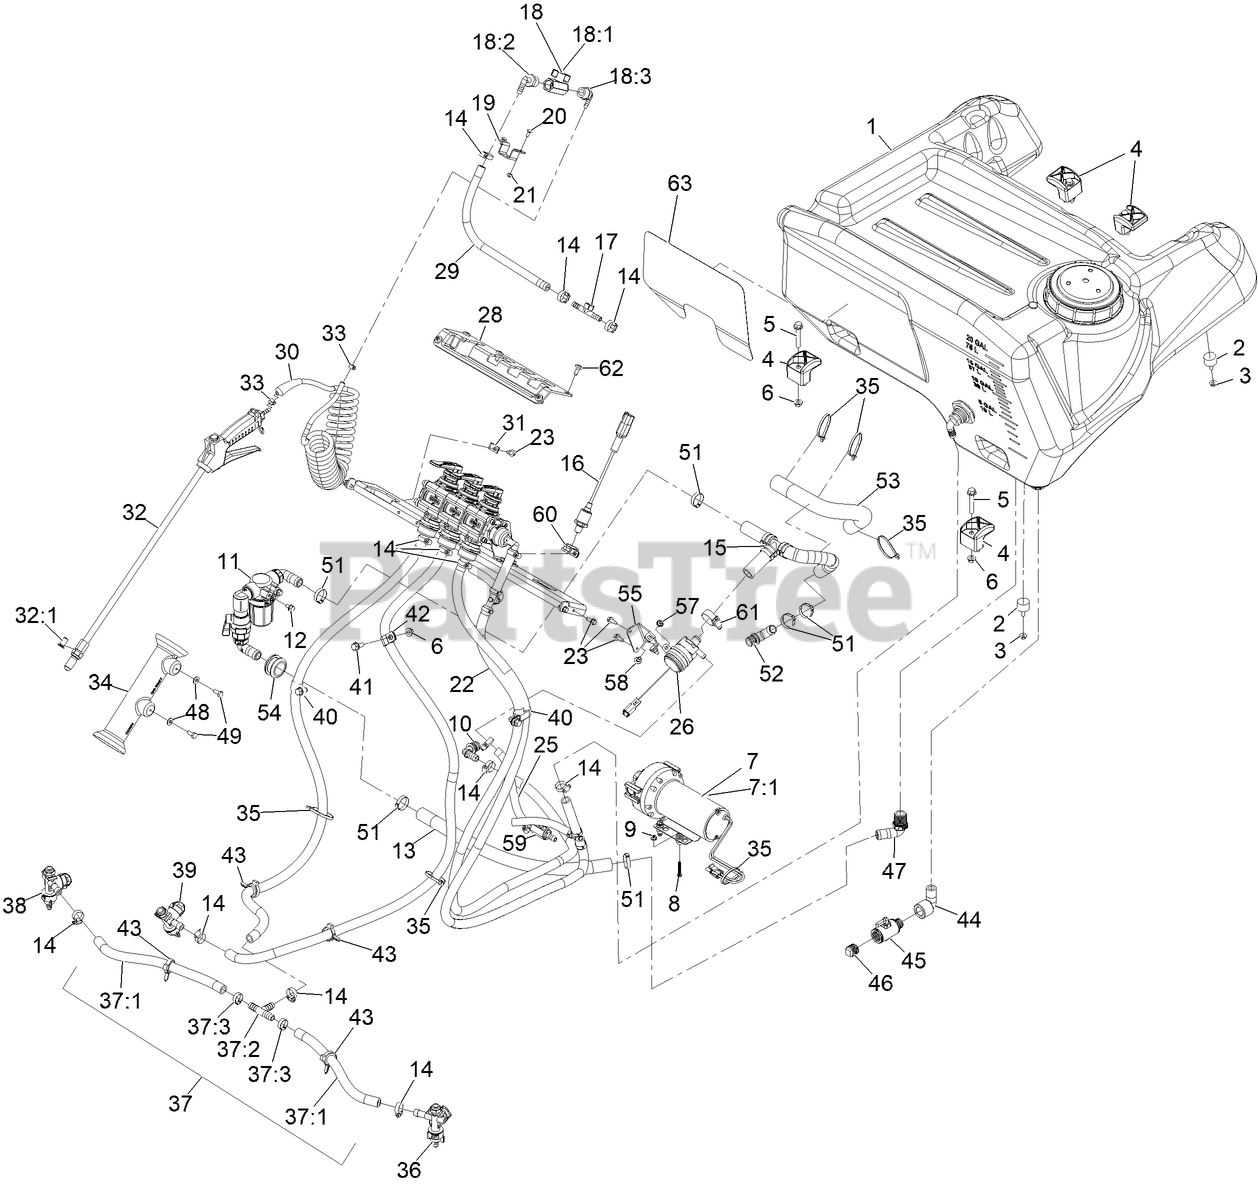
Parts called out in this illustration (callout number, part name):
1	Tank-Sprayer
5	SCREW-HHF
7	Pump-Diaphragm, 3.8 GPM
7:1	KIT-DIAPHRAM PUMP
8	SCREW-SHWH
10	FITTING-ELBOW, BARBED
11	STRAINER ASM
12	SCREW-HHF
13	HOSE-WATER
14	CLAMP-HOSE
15	ASM-, 3/4 Pvc Reinforced Water Hose
16	TRANSDUCER-PRESSURE
17	FITTING-TEE
18	Wand Control ASM
18:1	VALVE-BALL
18:2	FITTING-ELBOW-90
18:3	FITTING-ELBOW-90
19	BRACKET-VALVE
20	BOLT-CARR
21	NUT-LOCK, NI
22	Manifold-Valve, Control ASM
23	SCREW-HWH
25	Hose-Water
26	Pump-Centrifugal
28	Cover-Controls
29	HOSE-WATER, 3/8 PVC RED
30	Hose-Coiled, 04X15Ft
31	CLAMP-R
32	SPRAY WAND ASM
32:1	STRAINER-NOZZLE, 50M 5PSI
34	HOLDER-WAND
35	TIE-CABLE
36	LEFT NOZZLE SUB ASM
37	HOSE ASM
37:1	HOSE-WATER
37:2	FITTING-TEE
37:3	CLAMP OETIKER 0.716"" CLOSED 0.826"" OPEN
38	RIGHT NOZZLE SUB ASM
39	CENTER NOZZLE SUB ASM
41	SCREW-HHF
42	CLIP-LOOM
43	CLAMP-HOSE
44	ELBOW-90 DEG
45	MICROVALVE
47	ELBOW-HOSEBARB
48	WASHER-FLAT
49	SCREW-HH
52	FITTING-ELBOW
53	SLEEVE-CORRUGATED, SPLIT
54	GROMMET
55	Brkt-Recir Pump
58	SCREW-CARR
59	Valve-3/8 Check
60	R-Clamp
61	CLAMP-HOSE
62	SCREW-SHOULDER
63	Barrier-Heat
